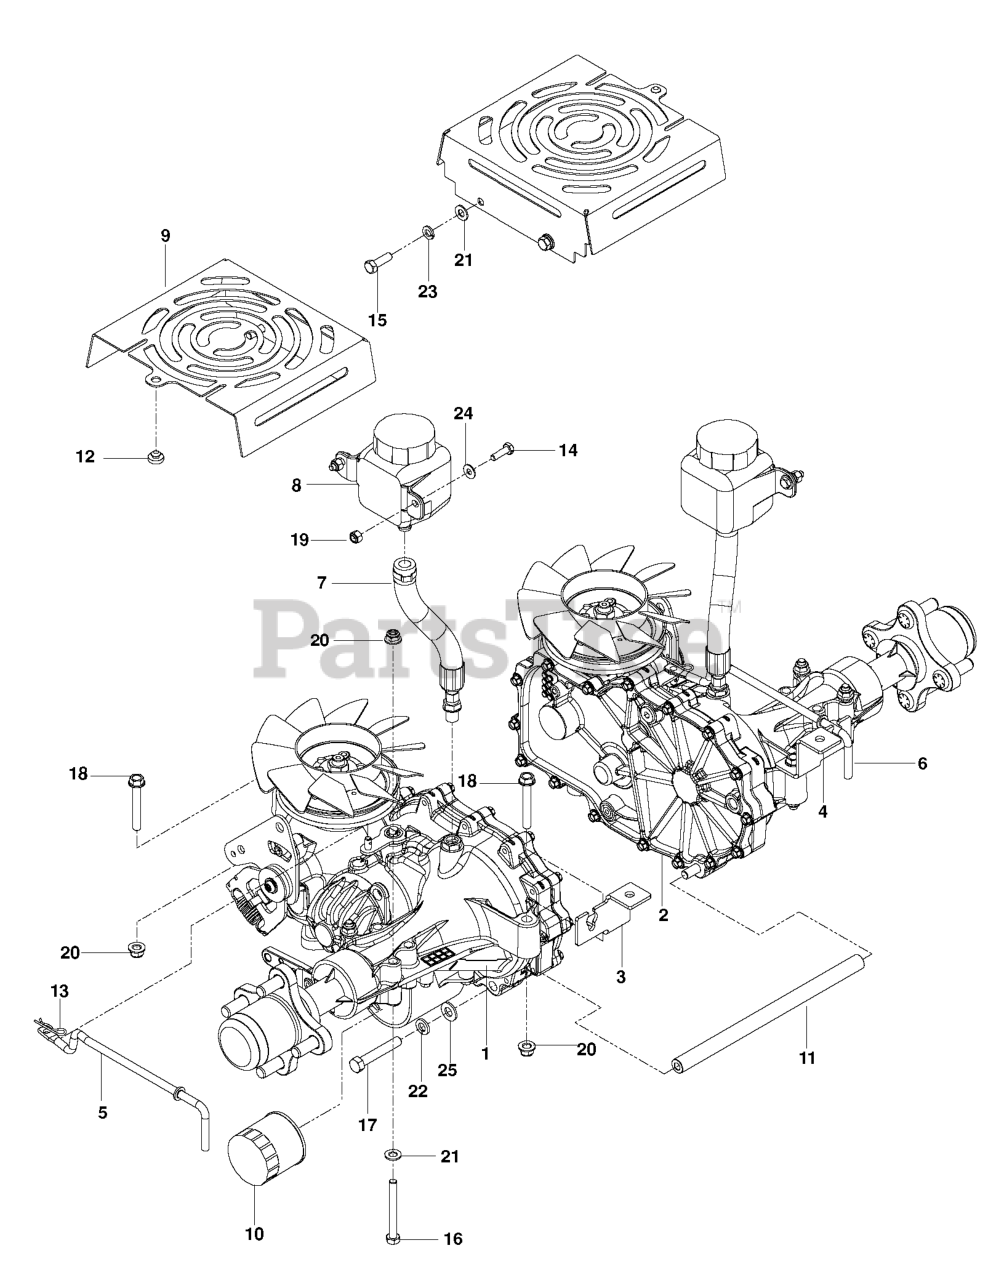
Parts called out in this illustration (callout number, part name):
1	HG_TRANS, ZT-3400, LT
2	HG_TRANS, ZT-3400, RT
3	BRACKET.TRANS.LT.BLACK
4	BRACKET, TRANS, RT BLACK
5	LINKAGE, LEFT BYPASS
6	LINKAGE, RIGHT BYPASS
7	HOSE ASSY, EXPANSION
8	TANK.EXPANSION.350ML 71328
9	SHIELD, FAN, BLK
10	HG_FILTER, ZT4800 52114
11	TUBE, SPACER, 3400
12	GROMMET, BUMPER
13	HAIRPIN #2
14	HCS 1/4-20X7/8 GR5
15	HCS 5/16C X 1
16	HCS 5/16C X 2-3/4
17	HCS 3/8-16X2-1/4 LOC PATCH GR8
18	HHFS 5/16-18 X 2.25 GD 5
19	NUT.1/4-20.HEX.NYLOC.ZD
20	5/16-18 NYLOC FLANGE NUT
21	FLAT WASHER 5/16 SAE
22	SLW 3/8 STD
23	WASHER.LOCK.HVY.HLCL.SPR.5/16
24	WASHER 1/4 SAE
25	WASHER 3/8 SAE FLAT
